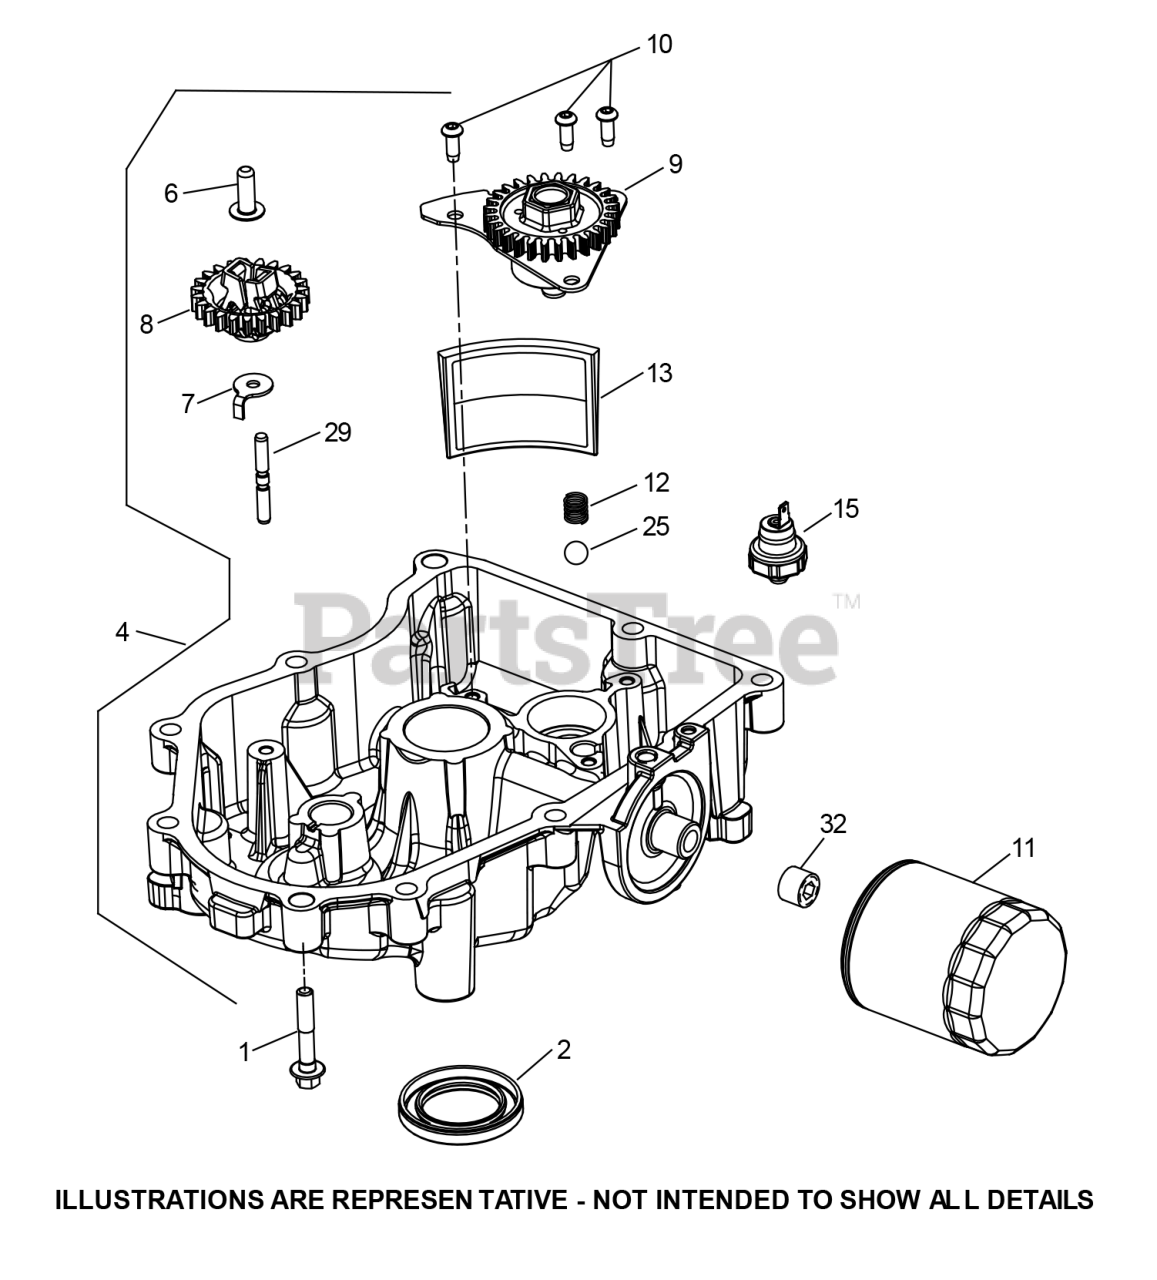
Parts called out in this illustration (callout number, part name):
6	PIN-GOV REGULATING
8	GEAR KIT-GOVERNOR
9	OIL PUMP ASSEMBLY
10	SCREW-BUTTON HEAD
11	OIL FILTER-SHORT (BOXED)
12	COMPRESSION SPRING
15	OIL PRESSURE SWITCH
25	PRESSURE RELIEF BA
29	GOVERNOR GEAR SHAFT
32	PLUG-3/8 HEX CTSK
